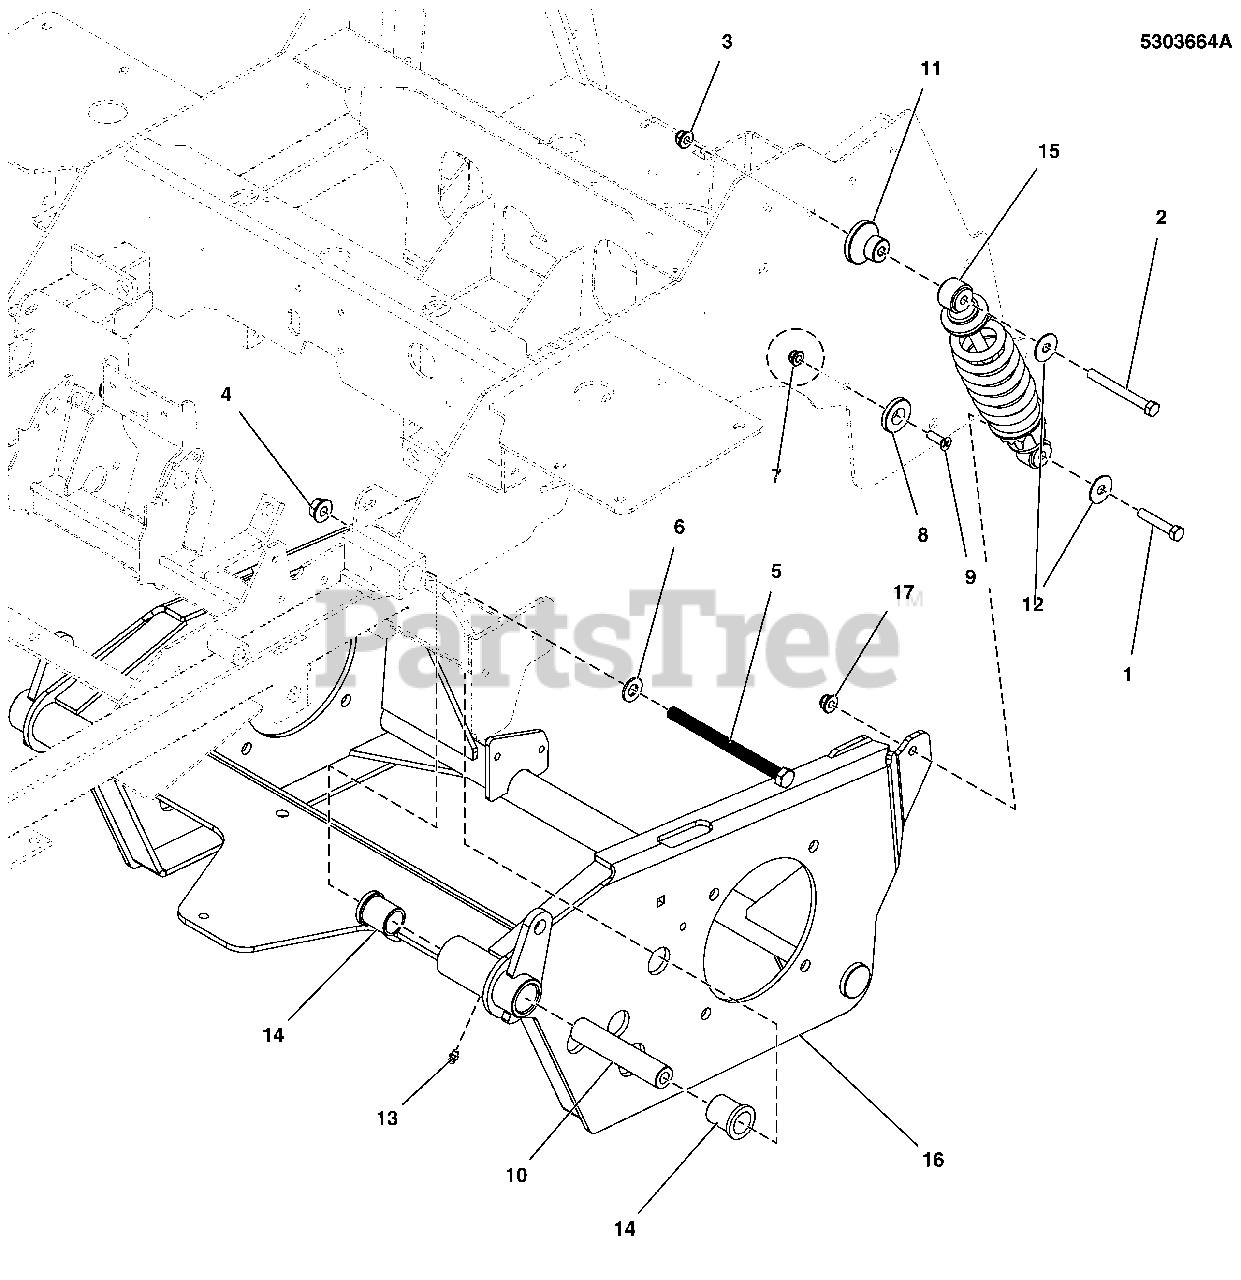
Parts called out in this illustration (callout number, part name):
1	BOLT, 3/8-16 X 2 GD5 YZ
2	BOLT, 3/8-16 X 3-1/2 GD5 CZ
3	NUT, 3/8-16 HEX NYLOCK FLANGE
4	NUT, 1/2-13 HEX NYLOCK FLANGE
5	BOLT, 1/2-13 X 6-1/2 GD8, YZ
6	WASHER, 1/2 SAE
7	NUT, 5/16-18 HEX NYLOCK FLANGE
8	SPACER, .34 X 1.54 X .25, PL
9	SCREW, 5/16-18X1, PHILLIPS HD. BZ
10	SPACER, .52 X 1.00 X 5.00
11	SPACER, .39 X 2.00 X 1.35, PM
12	WASHER-3/8 FENDER
13	GREASE FITTING, 1/4-28 STRAIGHT
14	BUSHING, FLANGE
15	SHOCK / SPRING ASSEMBLY, OE22376
16	WELD, TRANS CARRIAGE, IS2100 - ORG
17	NUT, 3/8-16 HEX SIDE LOCK
